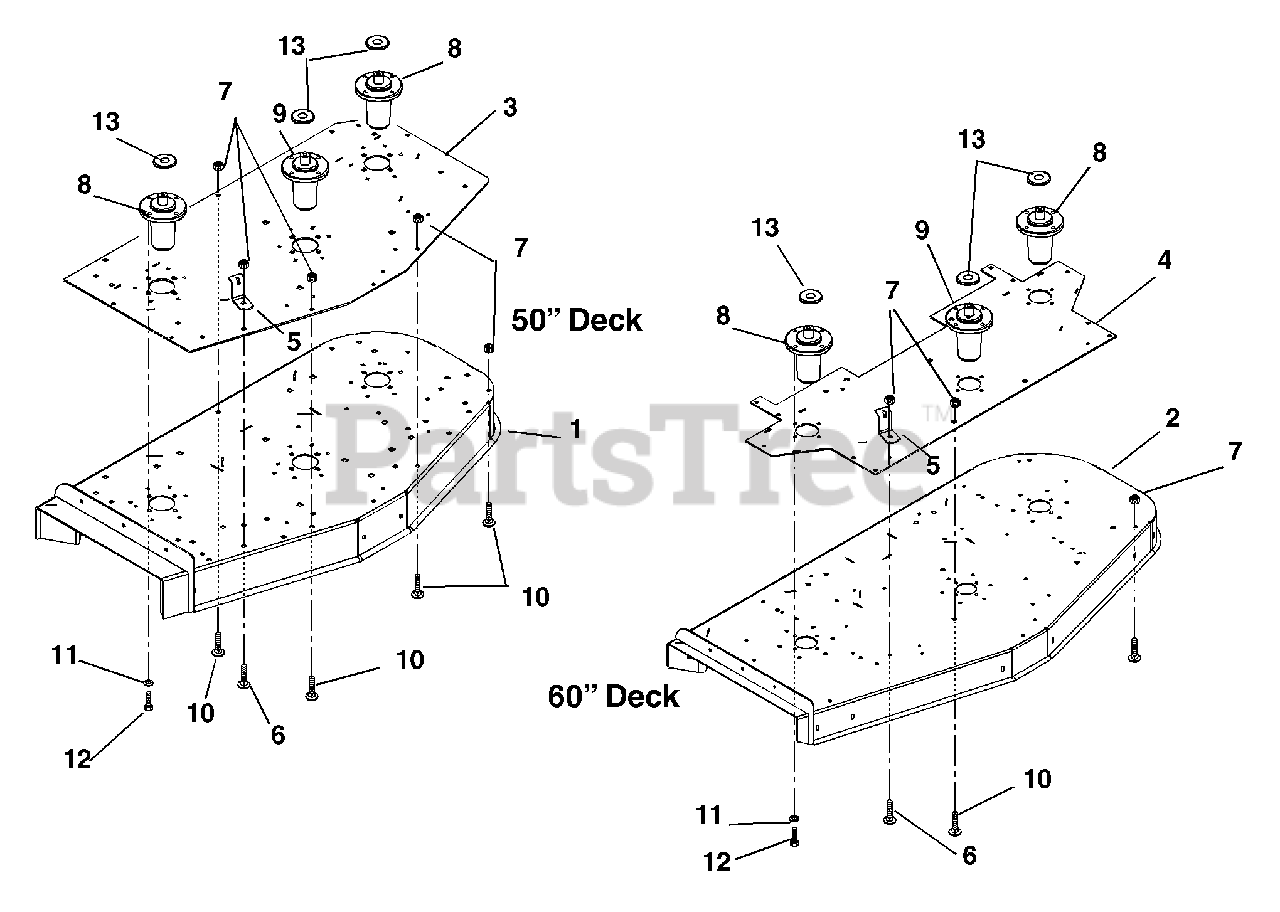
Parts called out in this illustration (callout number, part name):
1	Weldment, 50" Deck (Side Discharge)
2	Weldment, 60" Deck (Side Discharge)
3	Plate, 50" Reinforcement
4	Plate, 60" Reinforcing
5	Anchor, Spring
6	Bolt-Round Head Square Neck .38-16 x 1.25 Grade 2
7	Nut-Locking-Nylon .38-16 (50" Deck)
7	Nut-Locking-Nylon .38-16 (60" Deck)
8	Assembly, Spindle L-Hub
9	Spindle Assembly (Center)
10	Bolt-Round Head Square Neck .38-16 x 1.00 Grade 2 (50" Deck)
10	Bolt-Round Head Square Neck .38-16 x 1.00 Grade 2 (60" Deck)
11	Washer-Locking .38 x .094
12	Bolt-Hex .38-16 x 1.00 Grade 5
13	Slinger-Dust
